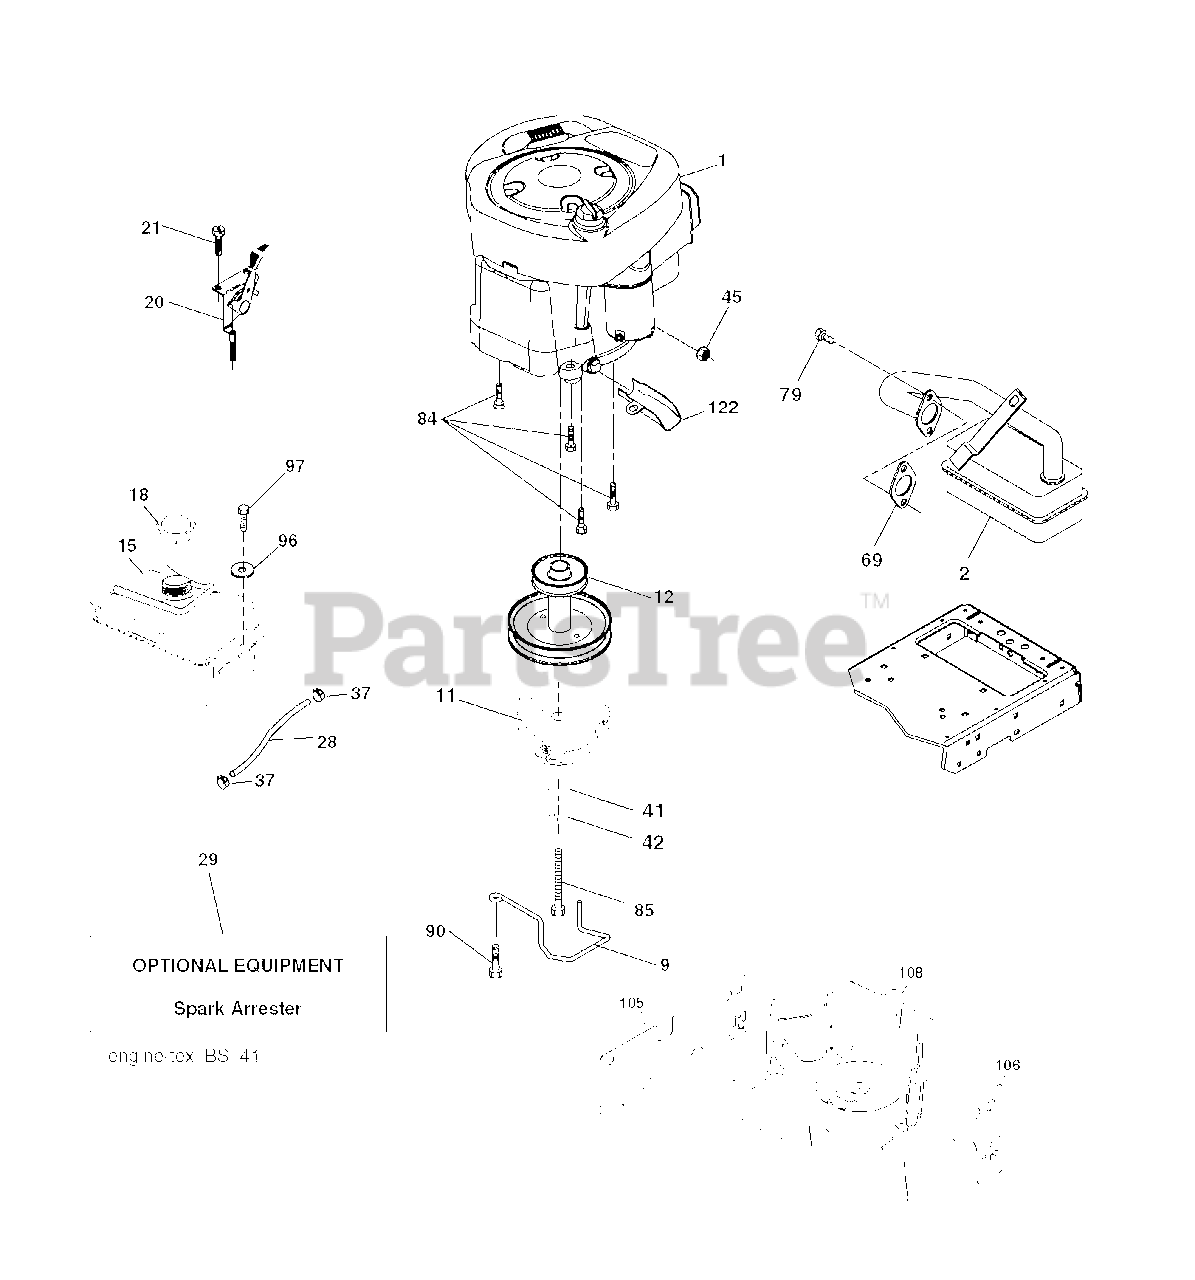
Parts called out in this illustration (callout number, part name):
9	KEEPER.BELT.ENGINE.3.25
11	CLUTCH
12	PULLEY.ASM.ENG.OGURA.3
15	TANK FUEL FRT 1.5 GAL
18	CAP ASM.FUEL.2.25"FR.
20	CONTROL.TH/CK.C.
21	SCREW.#10 X 0.750.BOS THREAD
28	LINE.FUEL.20
29	ARRESTER SPARK (OPTIONAL)
37	HOSE CLAMP
42	LOCKWASHER
45	NUT
69	REPL BY 532 27 22-93
79	SCREW.SOCKET HD.5/16-1
84	SCREW.3/8-16
85	BOLT HEX 7/16-20X4-1/4"
90	SCREW 3/8-16X1
97	SCREW HEXWSHR 1/4-20X3/4
122	EXTENSION DRAIN OIL
